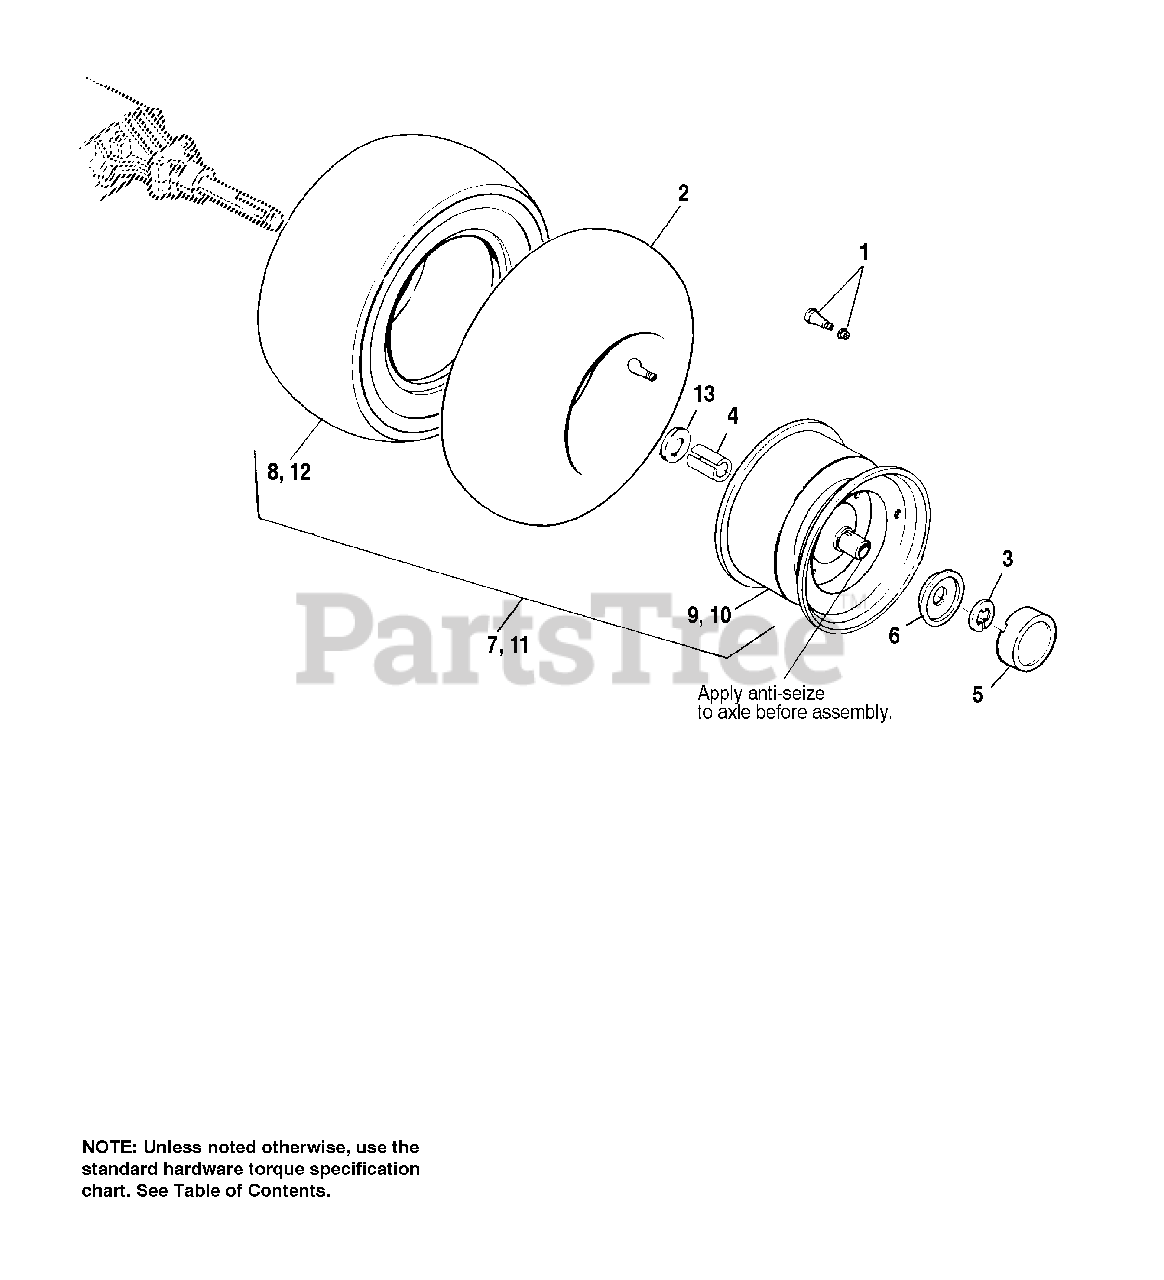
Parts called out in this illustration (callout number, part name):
1	VALVE STEM & CAP
2	TUBE
6	RETAINER, Cap, Hub
7	WHEEL & TIRE ASSY., 20 x 8.00-10
8	TIRE, 20 x 8.00-10
9	WHEEL ASSY., Metallic Gray, 20 x 8.00-10
10	WHEEL ASSY., Metallic Gray, 20 x 8.00-8
11	WHEEL & TIRE ASSY., 20 x 8.00-8
12	TIRE, 20 x 8.00-8
13	WASHER, 3/4
